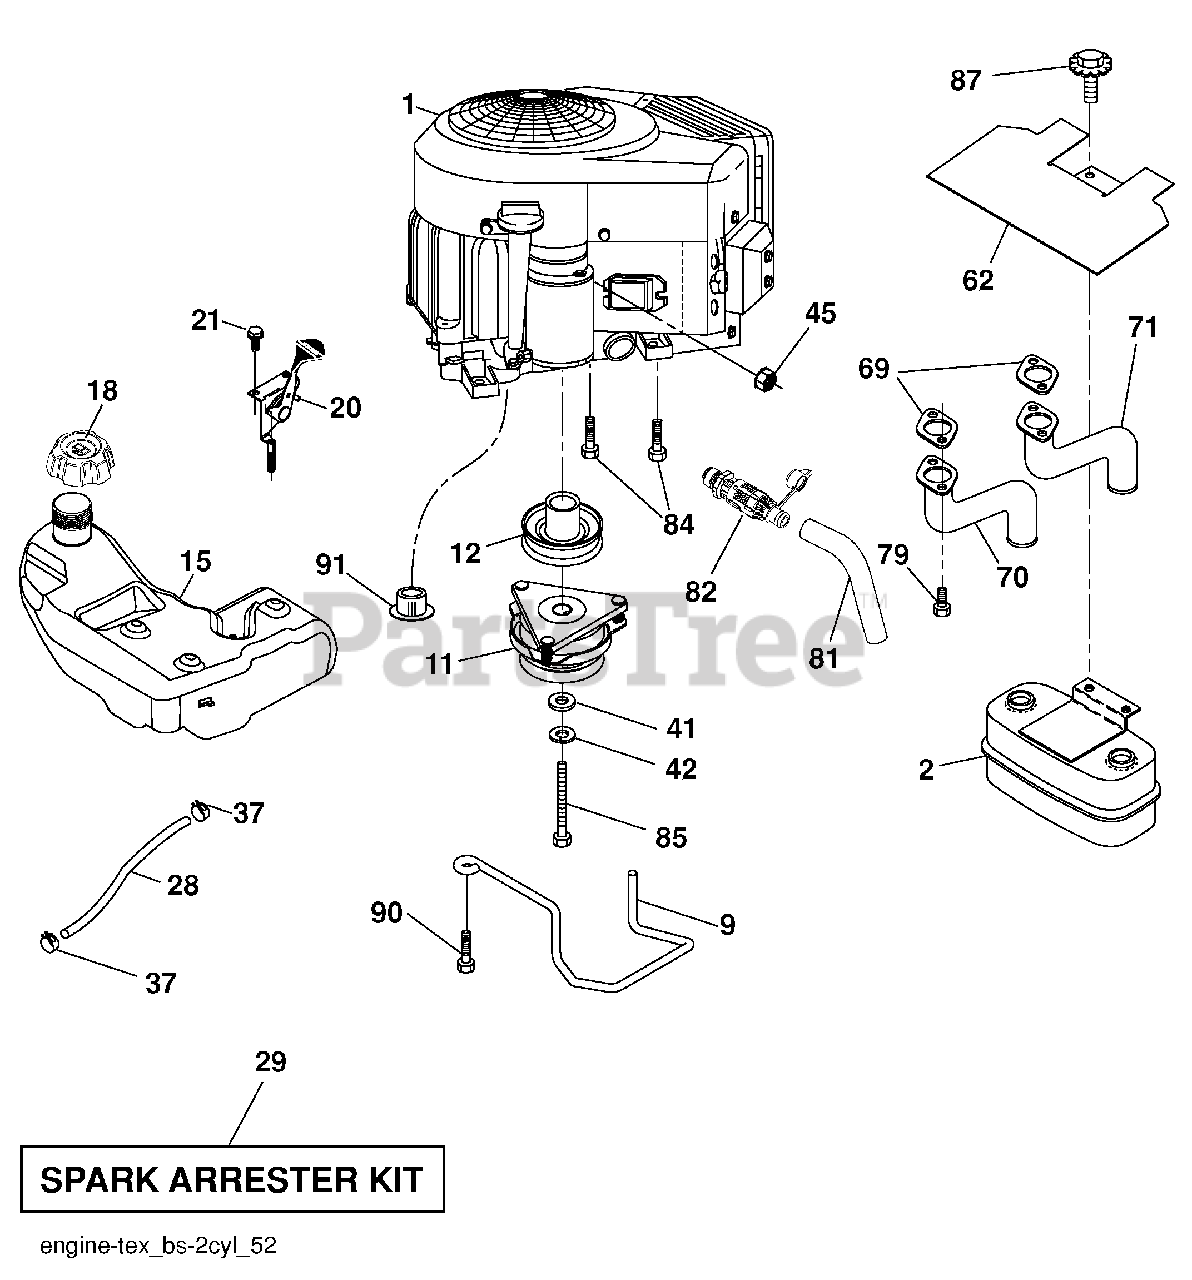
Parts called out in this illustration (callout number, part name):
9	Keeper Belt Engine
11	Clutch Electric
12	Pulley Engine
15	Tank Fuel
18	Cap Asm
20	Control Throttle
21	Screw #10 x 0.750 BOS Thread
28	Fuel Line
29	Spark Arrester Kit
37	Clamp Hose
41	Washer 1-1/2 OD x 15/32 ID x .250
42	Washer Lock 7/16
45	Nut Keps Hex 1/4-20 unc
62	Shield Heat Muffler
70	Tube Exhaust LH
71	Tube Exhaust RH
79	Screw Socket Head 5/16-18 x 1
81	Tube Drain Oil Easy
82	Drain Oil Valve
84	Screw 3/8-16 x 1-1/4
85	Bolt Hex 7/16-20 x 4 Cat. 5-1 THR.
87	Bolt 5/16-18 x 3/4
90	Screw 3/8-16 x 1
